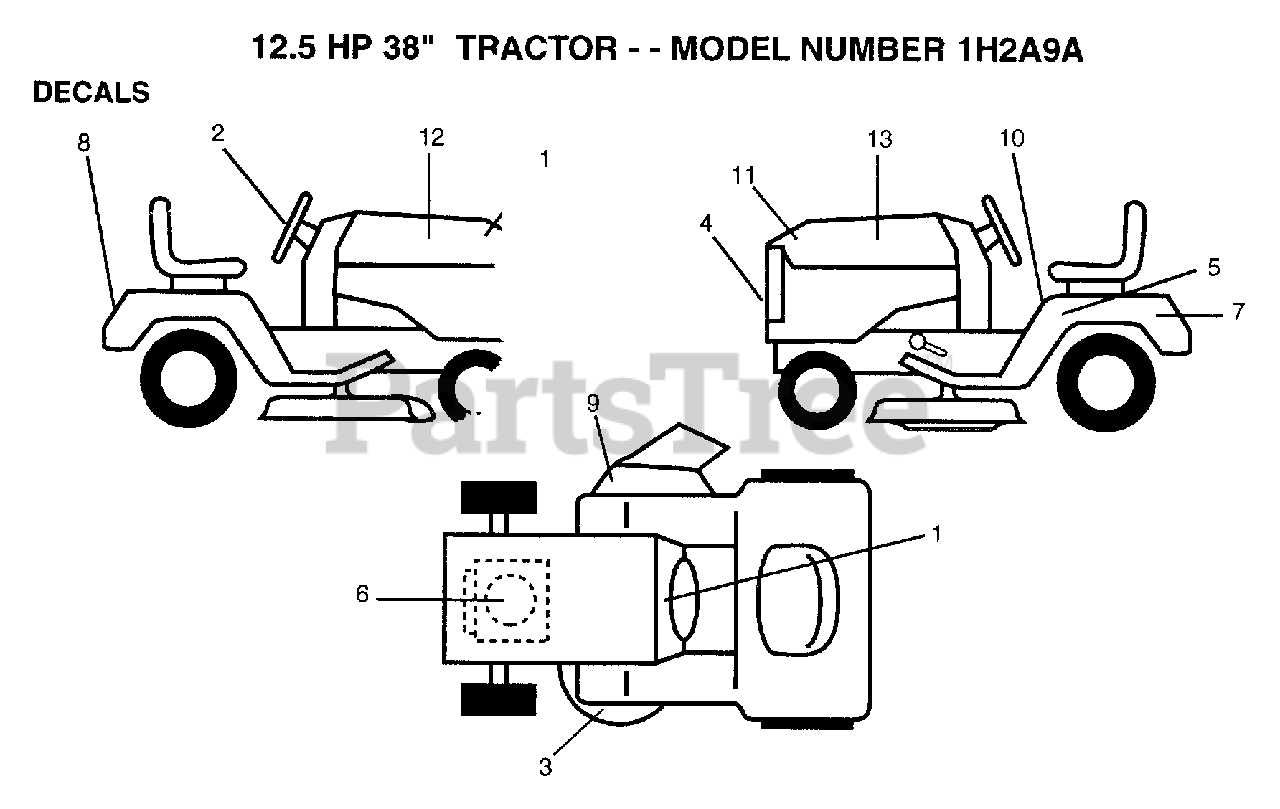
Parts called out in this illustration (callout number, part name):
2	"DECAL,STR WHL"
4	GRILL DECAL
5	IND HGT DECK DECA
7	DECAL
8	FENDER DECAL
9	"DECAL, WARNING"
10	DECAL CAUTION
12	"DECAL,STP HD RH"
13	"DECAL,STP HD LH"
